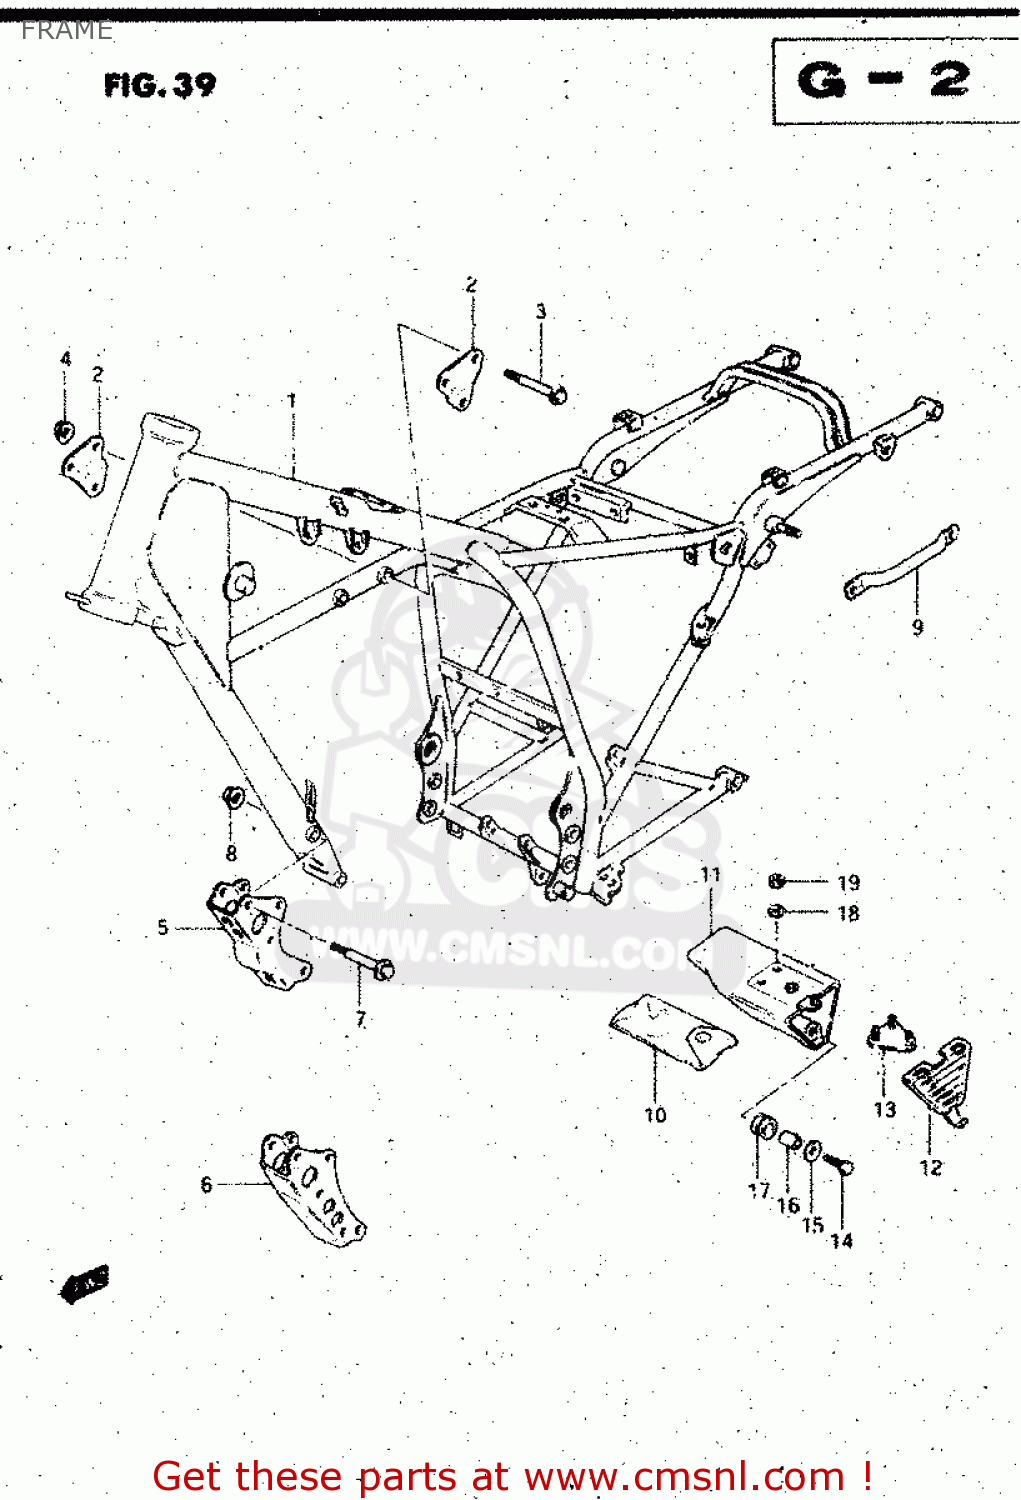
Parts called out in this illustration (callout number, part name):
1	FRAME (BLACK)
2	PLATE,ENGINE MOUNTING
3	BOLT
4	NUT
5	BRACKET,ENGINE MOUNTING LWR
6	PLATE, LOWER
7	BOLT
8	NUT
9	GRIP,STAND
10	TOOL SET
11	BOX,TOOL
12	CAP,TOOL BOX
13	PLATE,TOOL HOLDER
14	BOLT
15	WASHER (6.5X20X1.2)
16	SPACER(6.1X9X7.5)
17	CUSHION
18	WASHER
19	NUT
